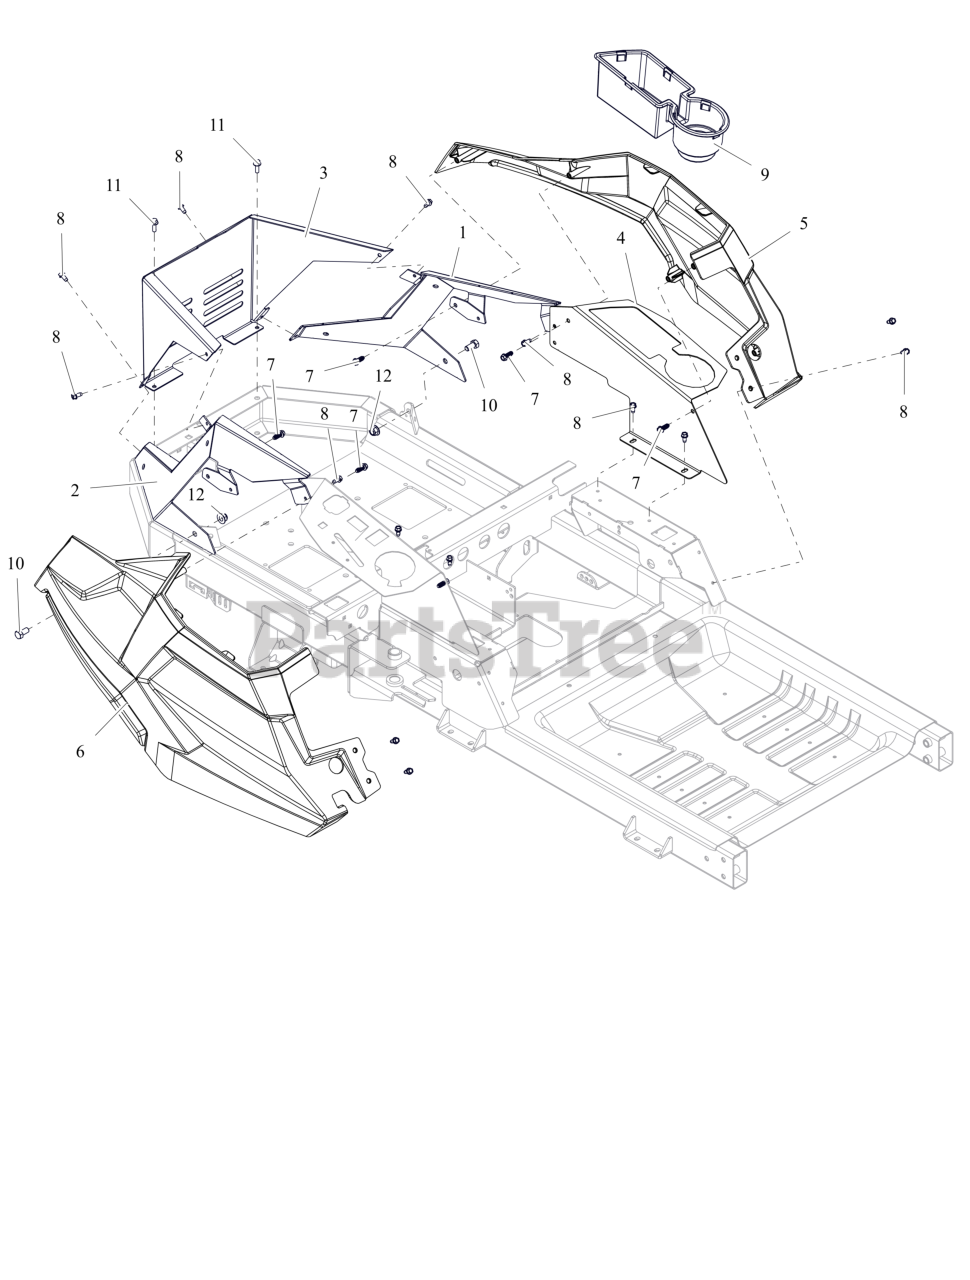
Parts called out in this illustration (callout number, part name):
1	WRAP, REAR - LH (RED)
2	WRAP, REAR - RH (RED)
3	WRAP, REAR (BLACK)
4	PANEL, CUP HOLDER (RED)
5	FENDER, LH
6	FENDER, RH
7	SCR-.312X.75 #14H H/W/H H/L CZ
8	SCR-TAP .25-20X.50 HWH ZCC
9	INSERT, CUP/STORAGE HOLDER
10	BLT,HEX .38-16X.75 G5 ZCC
11	BLT,HEX-FLG .25-20X.75 G5 BFP
12	NUT,NYL-FLG .38-16 GF ZCC
